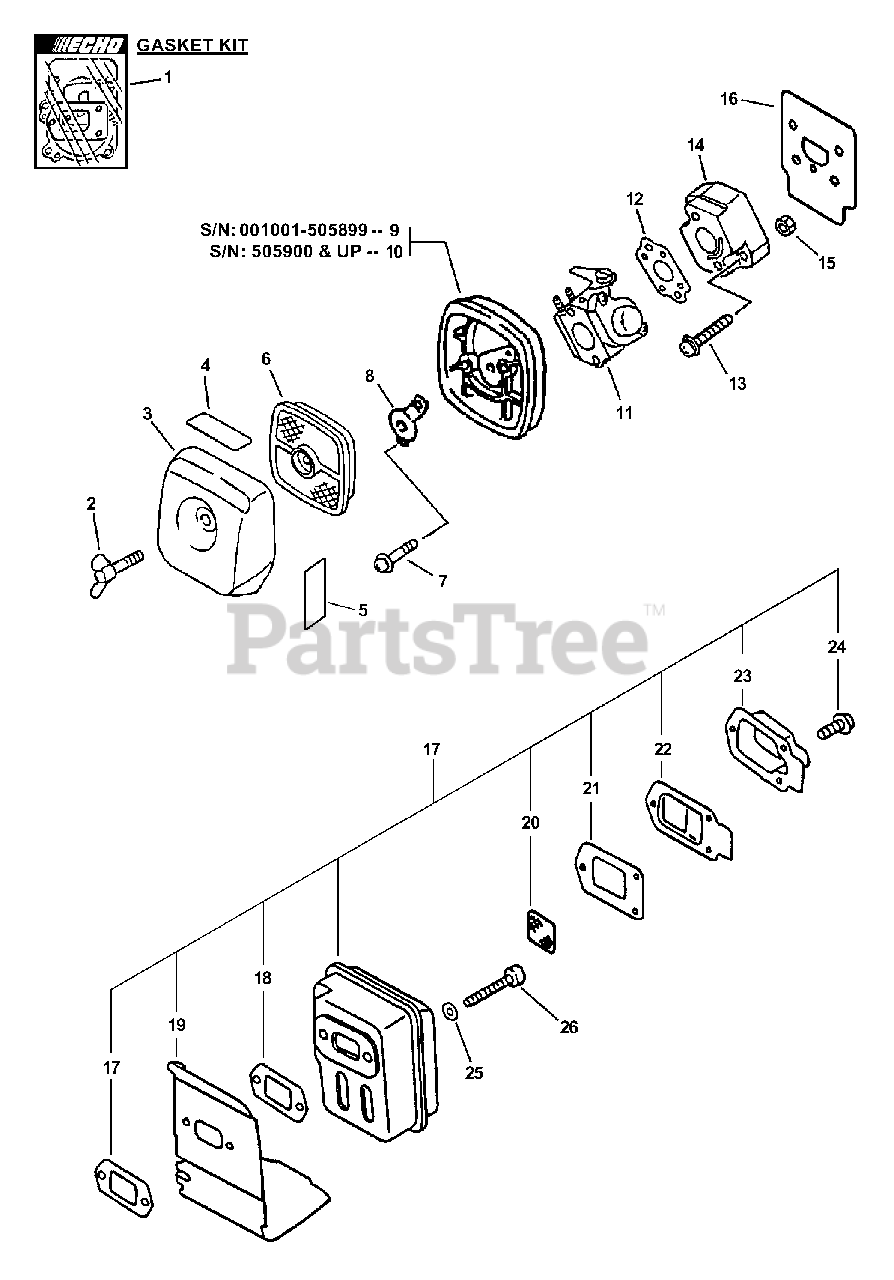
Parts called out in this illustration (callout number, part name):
1	GASKET KIT
2	BOLT, WING 5×20
3	COVER, AIR FILTER - BLACK
4	LABEL, CHOKE
5	LABEL, METERING
6	FILTER, AIR - SINGLE LAYER
7	SCREW 5×65
8	PLATE, PREVENT
9	CASE ASSY, AIR FILTER
10	CASE ASSY, AIR FILTER
11	CARBURETOR - WT-424B
12	GASKET, CARBURETOR
13	SCREW 5×20
14	INSULATOR, INTAKE
15	NUT M5
16	HEAT SHIELD, INTAKE
17	MUFFLER ASSY
18	GASKET, EXHAUST
19	COVER, EXHAUST
20	SCREEN, SPARK ARRESTER
21	GASKET, EXHAUST
22	GUIDE, EXHAUST
23	OUTLET, EXHAUST
24	SCREW 4×10
25	WASHER, FLAT 5.5×10×0.8
26	BOLT 5×55
